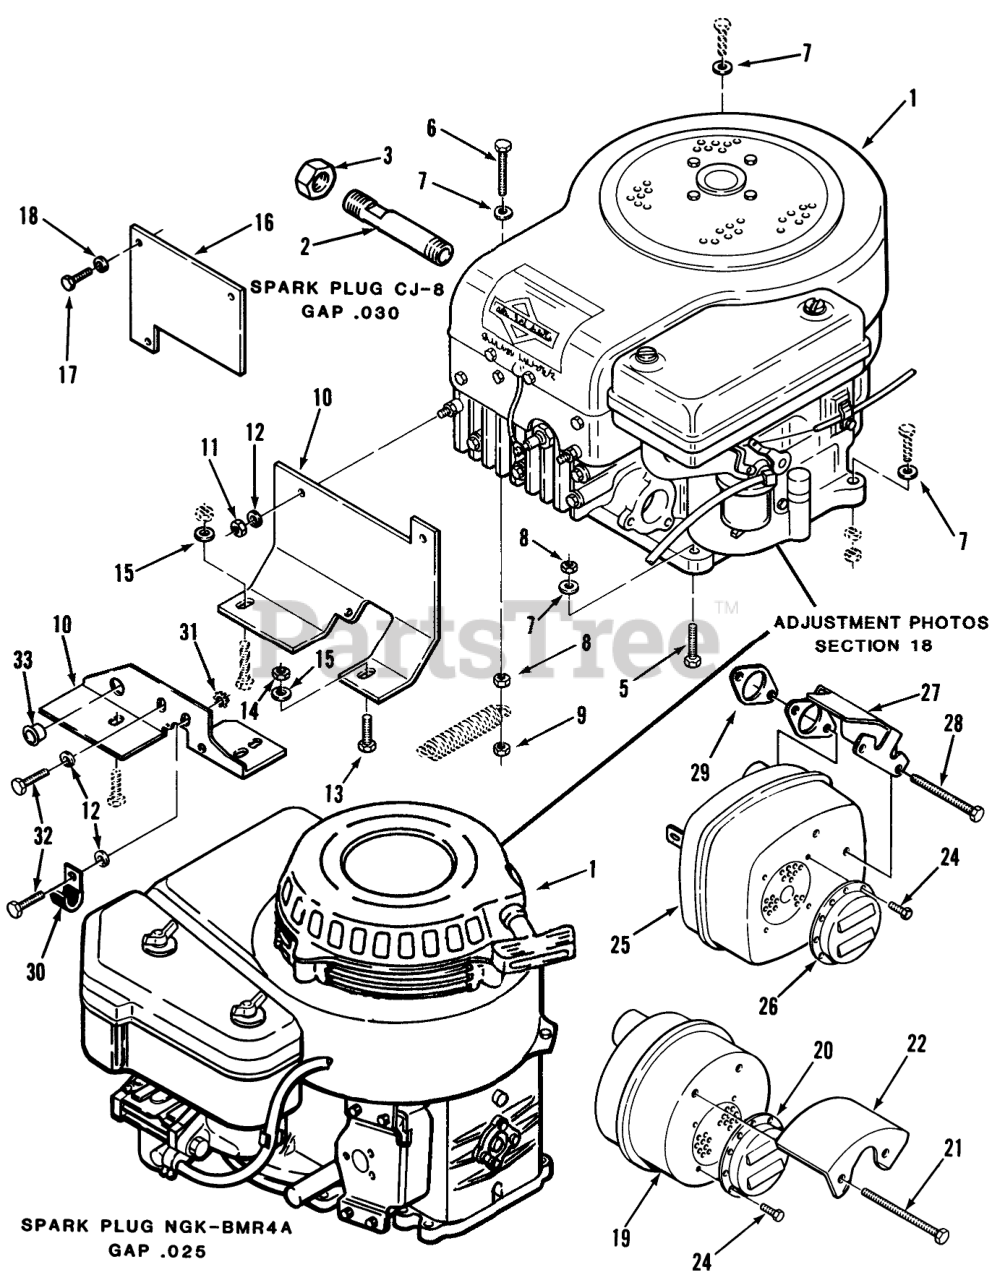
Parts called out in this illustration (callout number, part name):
1	Engine-8 HP B&S Model 190702 Type 2176-01 108-R Only
2	PIPE-DRAIN B
3	Cap
5	Bolt
6	Bolt 5/16-18 x 2
7	WASHER 5/16 SAE
8	Nut
9	Nut
10	BRACKET ENGINE HE R
11	Nut
12	Lockwasher
13	Bolt
14	NUT
15	Washer
16	PLATE SPRING B
17	Bolt
18	Washer
19	MUFFLER
20	HEAT SHIELD
21	Bolt, 5/16-18 x 1/4
22	DEFLECTOR MUFFLER
24	SCRW-HX S.T.#8 X 3/8
25	MUFFLER
26	Muffler Deflector 112-C Only
27	HEAT-SHIELD
28	Bolt 8M x 1.25 x 110 112-C Only
30	CLIP
31	Washer-Lock
32	Bolt 8M x 1.25 x 16 112-C Only
33	BUSHING-NYLON 1.093
